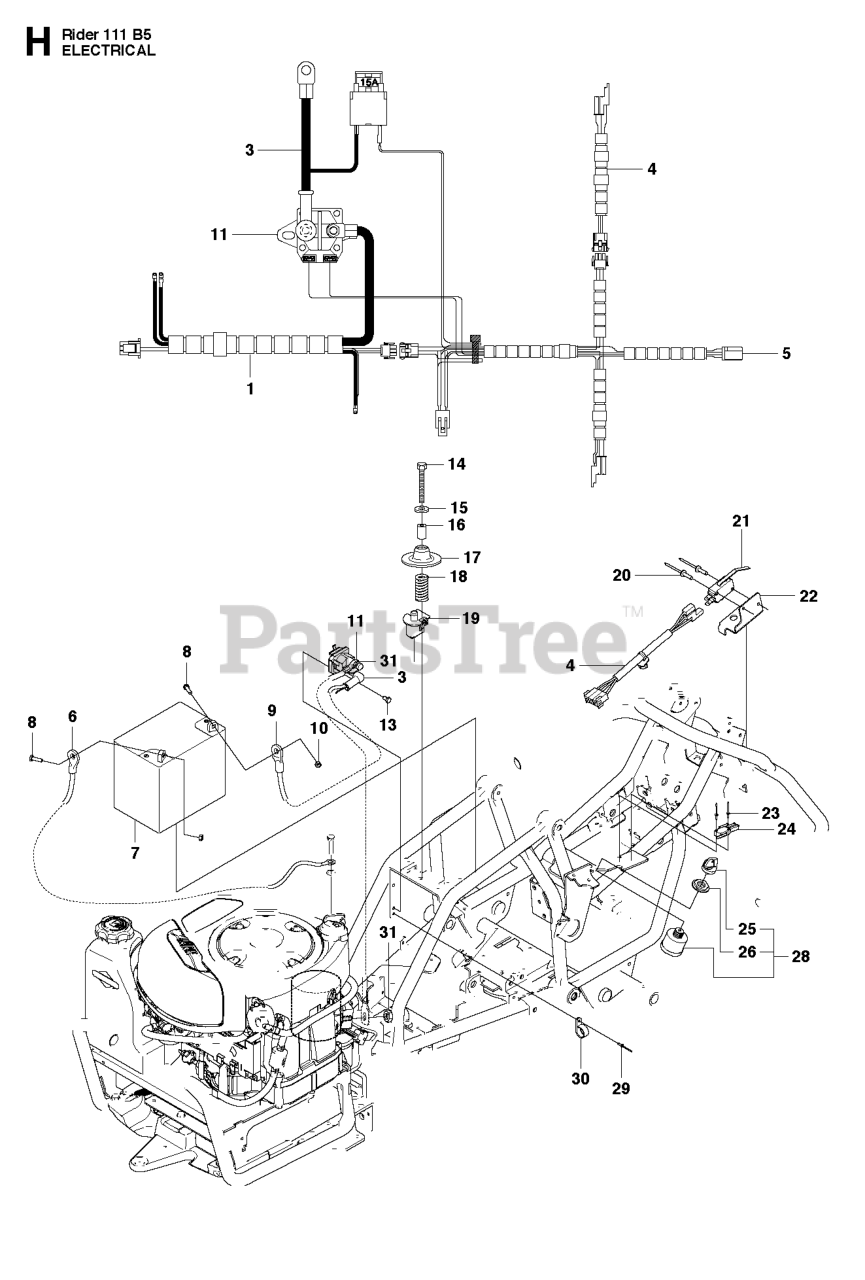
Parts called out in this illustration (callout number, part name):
8	SCREW EHHM
14	SCREW
16	SPACER TUBE
21	MICRO SWITCH
24	MICRO SWITCH
25	IGNITION KEY
26	NUT
28	IGNITION SWITCH
30	CABLE CLAMP
